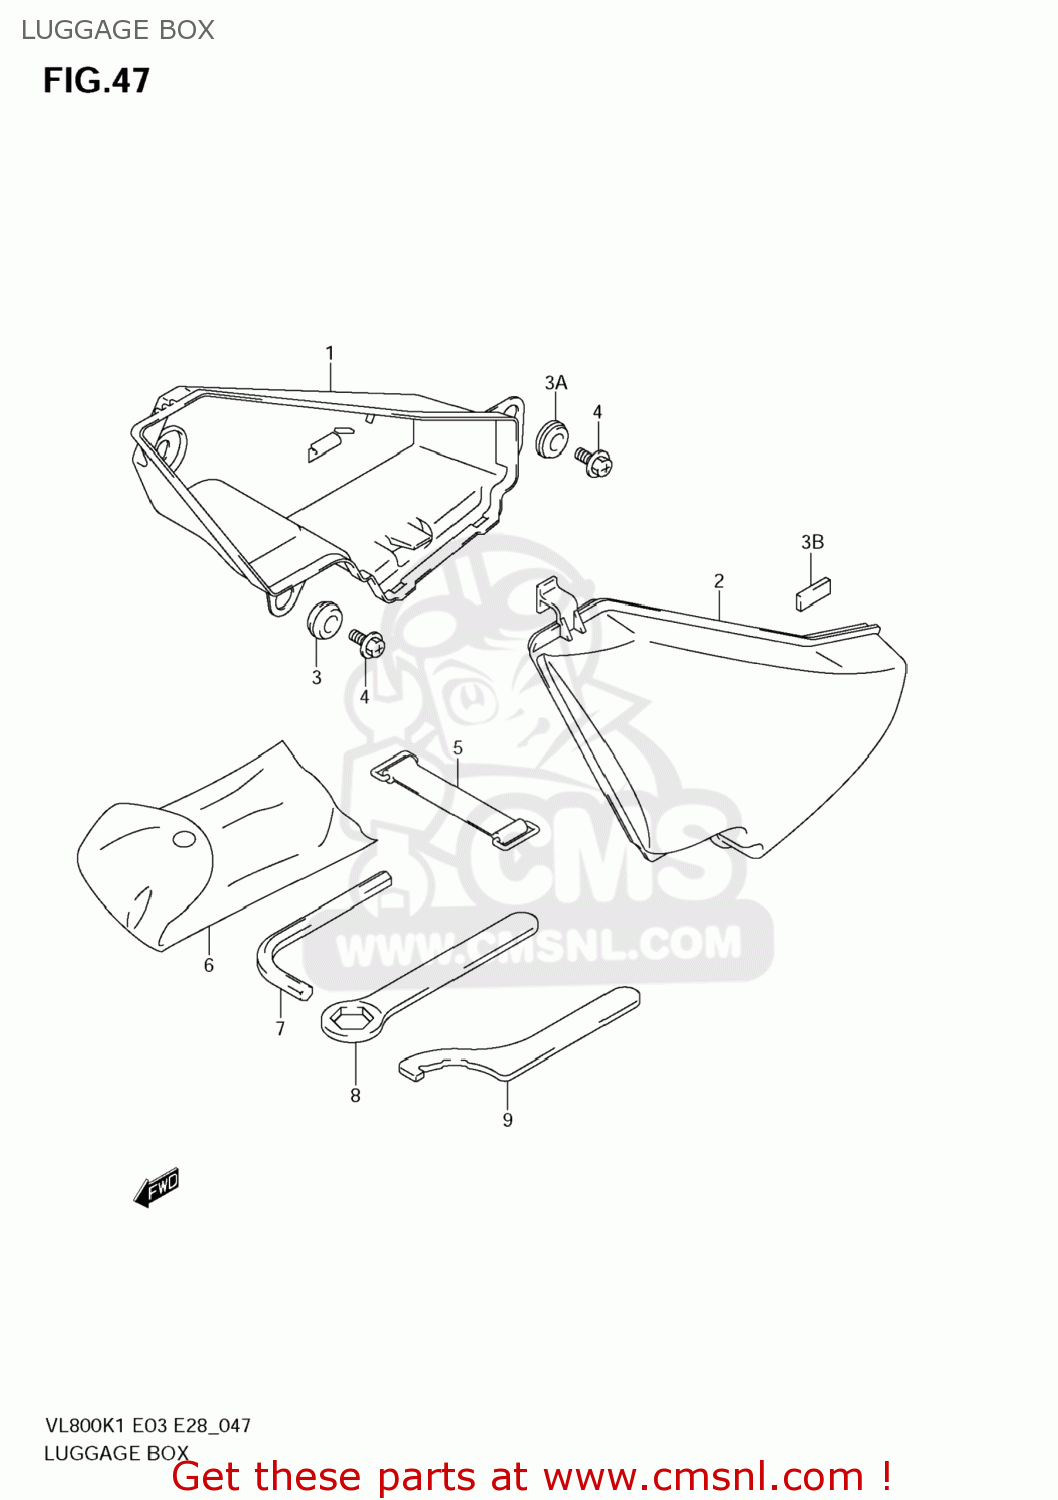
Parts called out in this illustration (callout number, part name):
1	BODY,LUGGAGE BOX
2	LID,LUGGAGE BO
3	CUSHION
3A	CUSHION
3B	CUSHION,LUGGAGE BOX NO.2
4	BOLT
5	BAND
6	TOOL ASSY
7	HEXAGON SPANNER,8
8	RING SPANNER(22)
9	CLAMP
